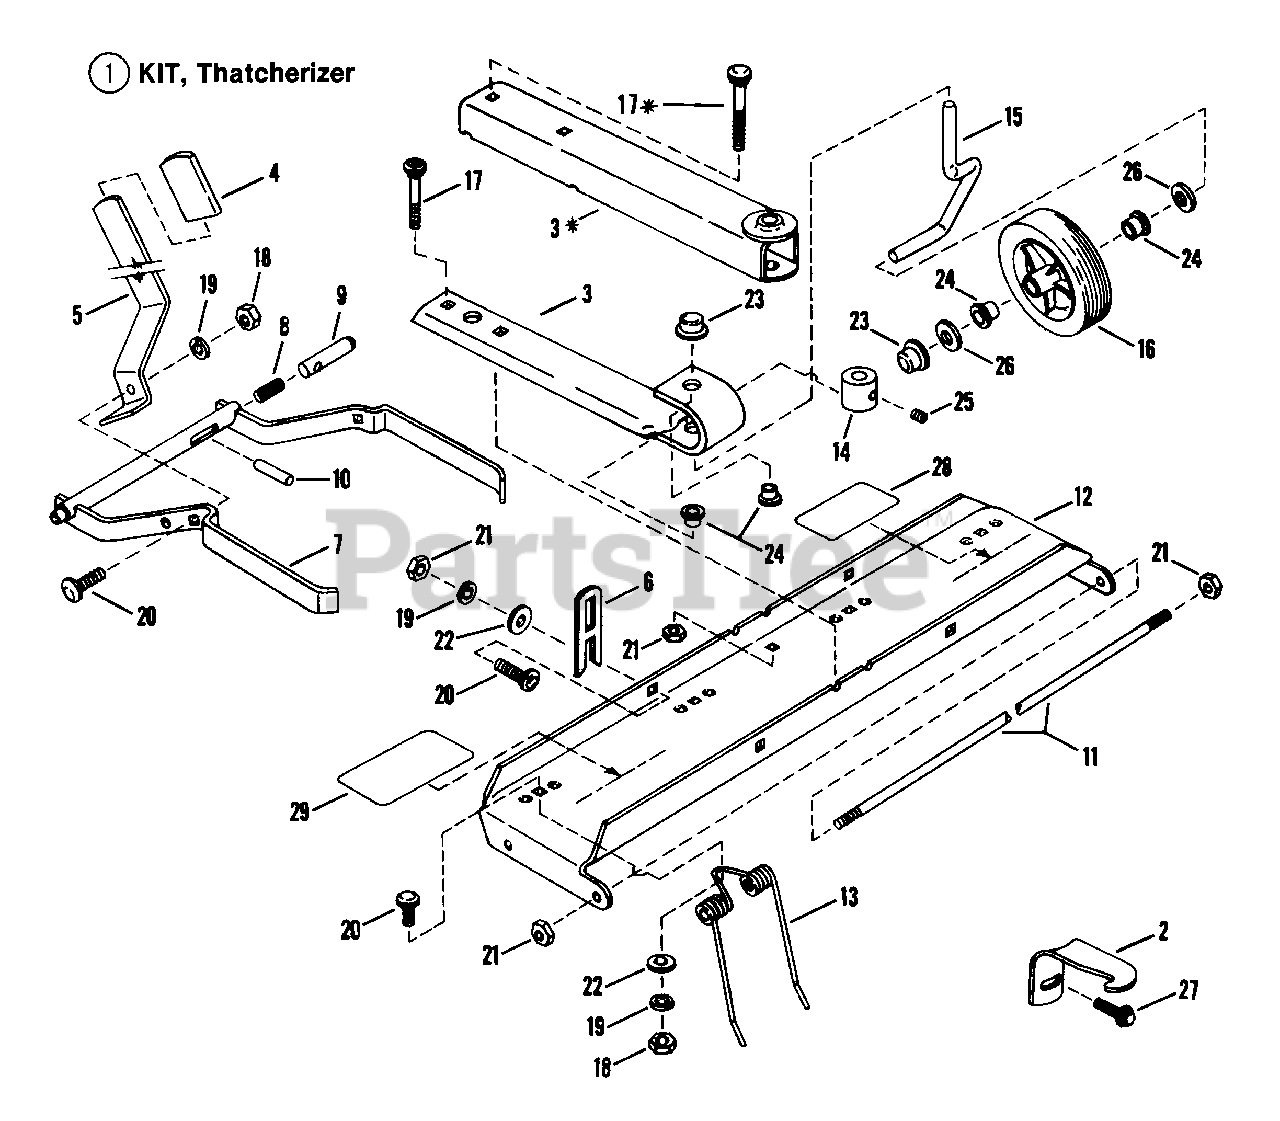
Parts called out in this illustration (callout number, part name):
1	KIT, Thatcherizer
2	BRACKET, Transport Lock
3	SUPPORT, Wheel Assembly
4	GRIP, Handle
5	HANDLE, Lift
6	STRAP, Frame Mount
7	FRAME, Thatcherizer
8	SPRING, Compression
9	PIN, Locking
10	ROLL-PIN
11	ROD, Tine Retainer
12	TRAY,Tine (28")
13	SPRING, Tine Thatching
14	BUSHING
15	AXLE,Wheel
16	WHEEL, 7"
17	CARRIAGE BOLT, 1/4-20x1 3/4"
18	NUT, 5/16-18 Hex (9)
19	LOCKWASHER, 5/16 Split
20	CARRIAGE BOLT, 5/16-18x1"
21	LOCKNUT, 1/4-20 Hex
22	WASHER, Reinforcing
23	PUSH-NUT, 1/2"
24	BEARING, Nyliner, Snap-In
25	SET-SCREW, 5/16-18x1/4" Slotted
26	WASHER, 1/2" SAE
27	SCREW, 5/16-18x3/4" HHS-Tapping
28	DECAL, Instruction
29	DECAL, Thatcherizer
